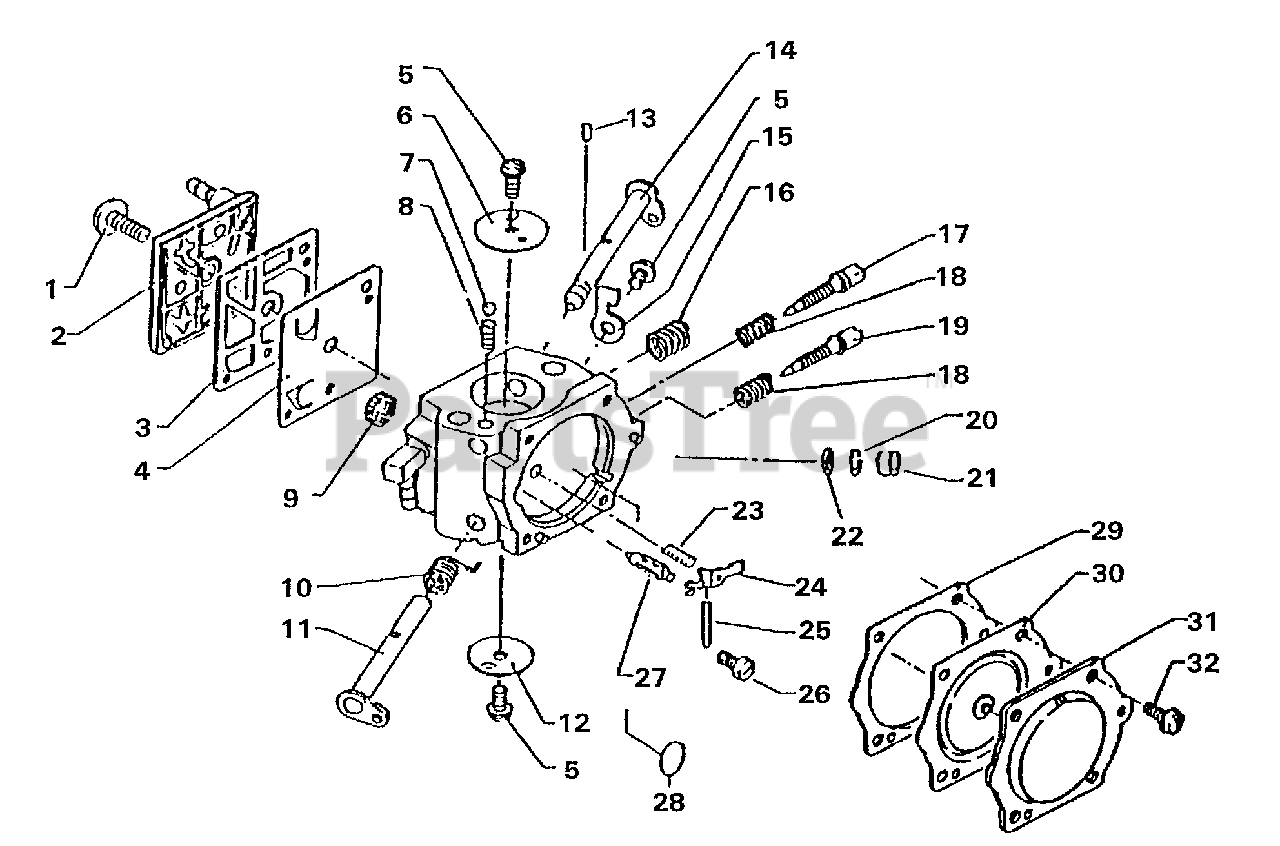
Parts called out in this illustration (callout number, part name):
1	SCREW, PUMP COVER
2	COVER, PUMP
3	GASKET, PUMP
4	DIAPHRAGM, PUMP
6	VALVE, CHOKE
7	BALL, CHOKE
9	STRAINER
10	SPRING, THROTTLE RETURN
11	SHAFT, THROTTLE
12	VALVE, THROTTLE
14	SHAFT, CHOKE
15	STOP, THROTTLE
16	SPRING, IDLE ADJUST
17	NEEDLE - LOW SPEED
18	SPRING
19	NEEDLE - HIGH SPEED
20	RING, RETAINING
21	PLUG, WELCH
22	STRAINER
23	SPRING, METERING LEVER
24	LEVER, METERING
25	PIN, METERING LEVER
26	SCREW, METERING LEVER PIN
27	VALVE, INLET NEEDLE
28	PLUG, WELCH
29	GASKET, METERING
30	DIAPHRAGM, METERING
31	COVER, METERING
32	SCREW
